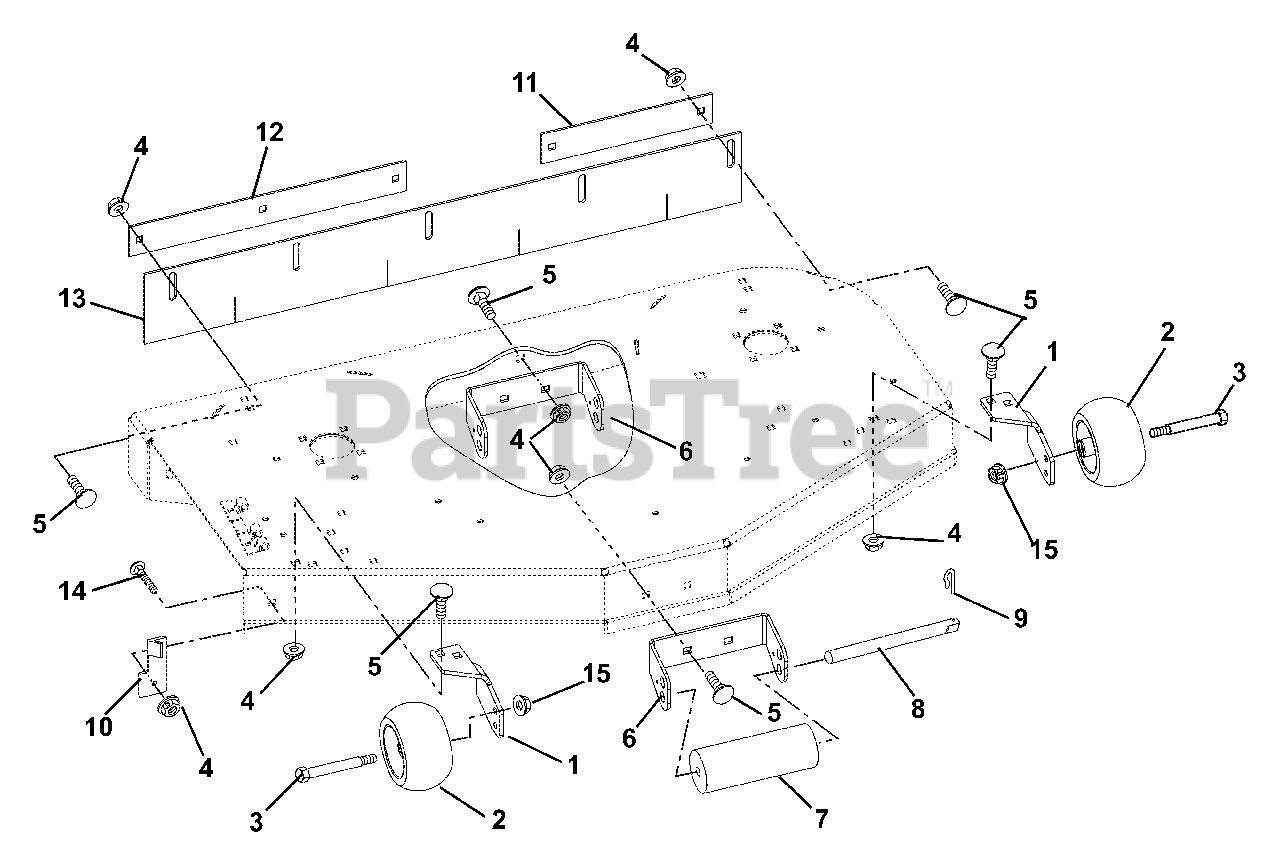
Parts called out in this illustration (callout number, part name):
1	Bracket, Anti-Scalp
2	Wheel 5 x 3
3	Bolt, Shoulder .38-16 x 2.50 Hex Washer Head Grade 5
4	Nut .38-16 Flange Nyloc
5	Bolt-Round Head Square Neck .38-16 x 1.00 Grade 5
6	Bracket, Roller Mount
7	Roller
8	Pin, Roller
9	Pin, Spring Clip
10	Bracket, Chute Lock
11	Bar, Left Hand Retainer Striper
12	Bar, Retaining Striper (044)
12	Bar, Retaining Striper (046)
12	Bar, Retaining Striper (048, 050)
13	Striper, Rubber-40" (044)
13	Striper, Rubber-44" (046)
13	Striper, Rubber-48" (048)
13	Striper, Rubber-52" (050)
14	Bolt, Round Head Square Neck .38-16 x 1.50
15	Nut-Locking-Top-Flange .38-16
